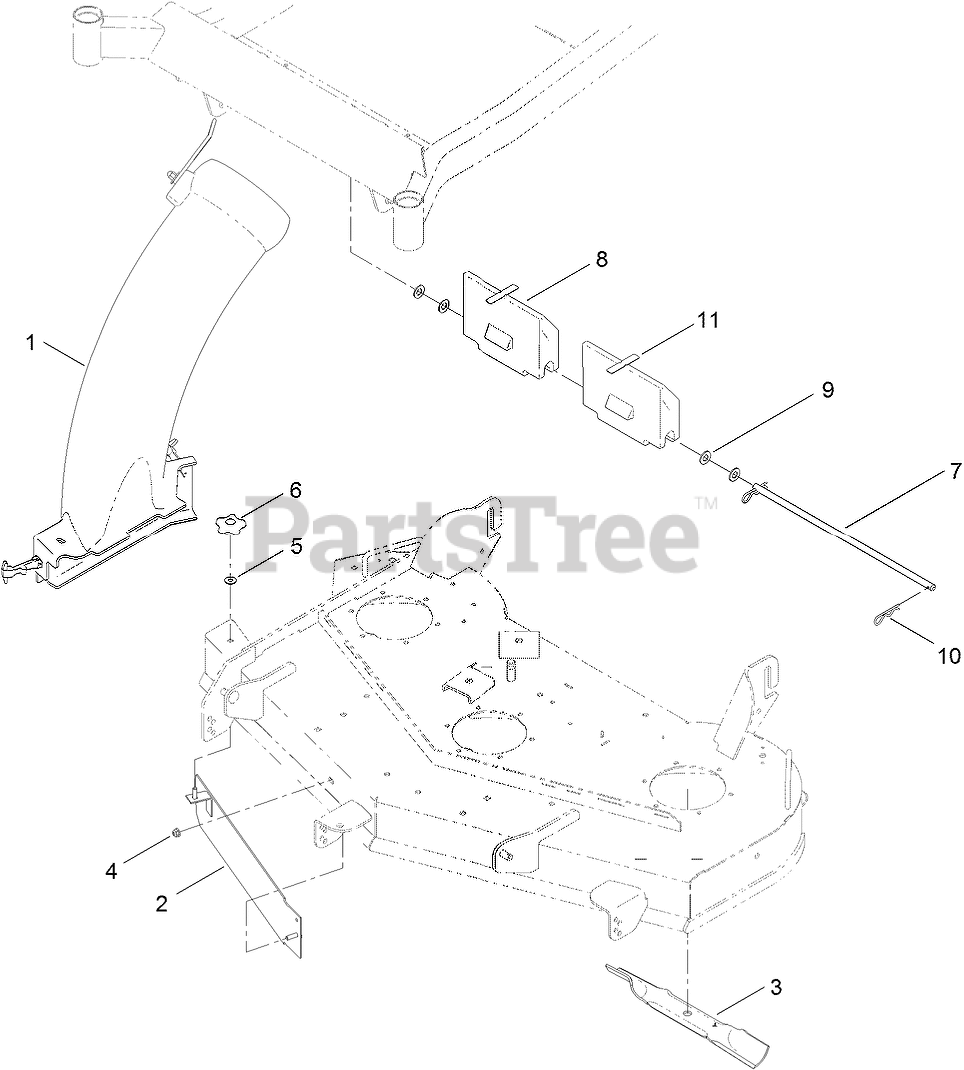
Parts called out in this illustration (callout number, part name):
1	CHUTE ASM
3	BLADE-HI LIFT, 16.50 IN
4	NUT-HF, NI
5	WASHER-FLAT
6	KNOB-LOCKING
7	ROD-DECK, PIVOT
8	WEIGHT-BAGGER
9	WASHER-FLAT
10	PIN-HAIR
11	BUMPER-PAD
